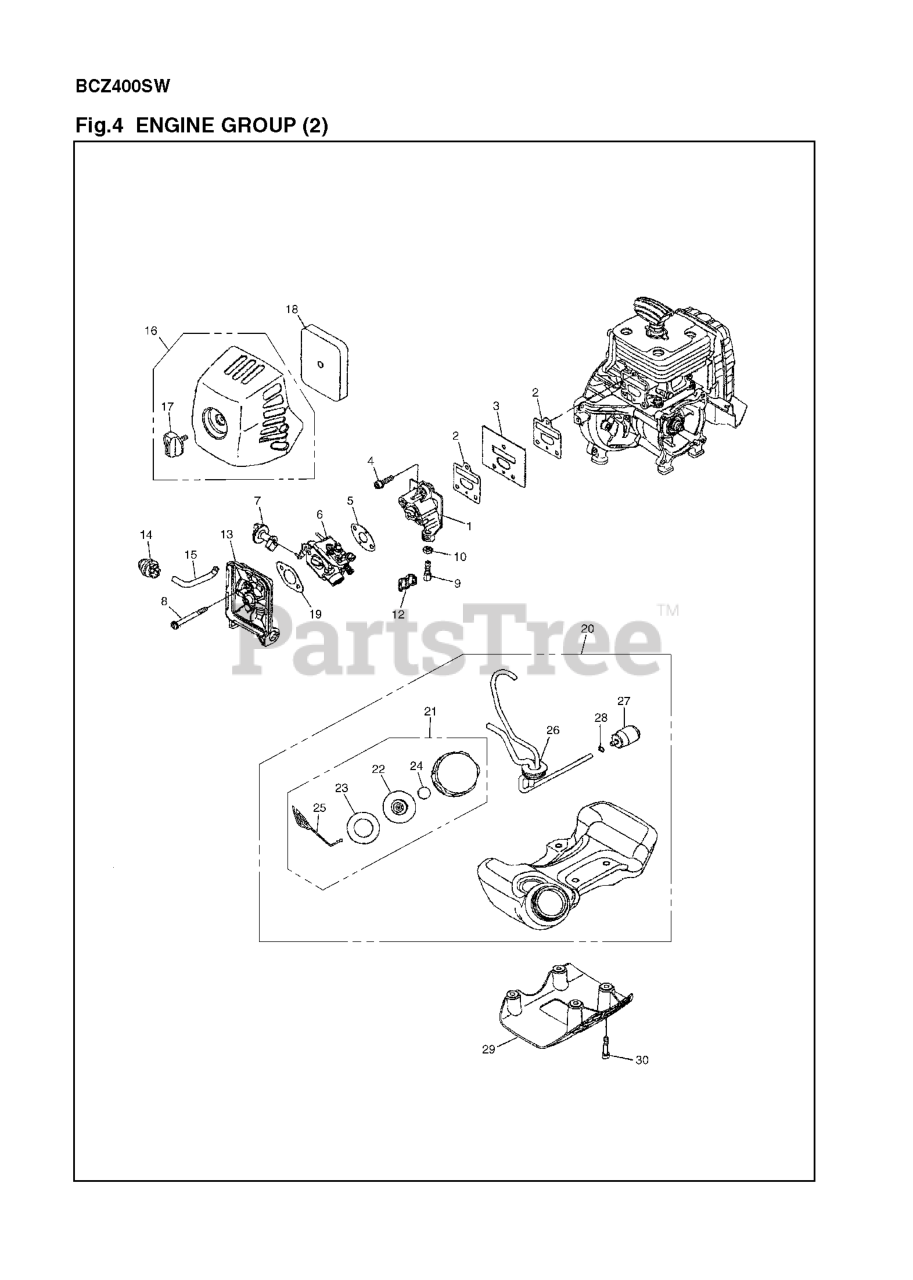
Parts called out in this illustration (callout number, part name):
1	INSULATOR
4	BOLT TORX
6	CARBURETOR ASSY WTEA-4A
8	BOLT TORX
9	ADJUSTER
10	NUT
14	PRIMARY BTN
15	PIPE L70
16	COVER ASSY
17	Cleaner Knob
20	TANK ASSY
21	ASSY FUEL CAP
22	HOLDER-A
26	PIPE ASSY
27	FILTER ASSY
28	CLIP
30	BOLT M5X25
